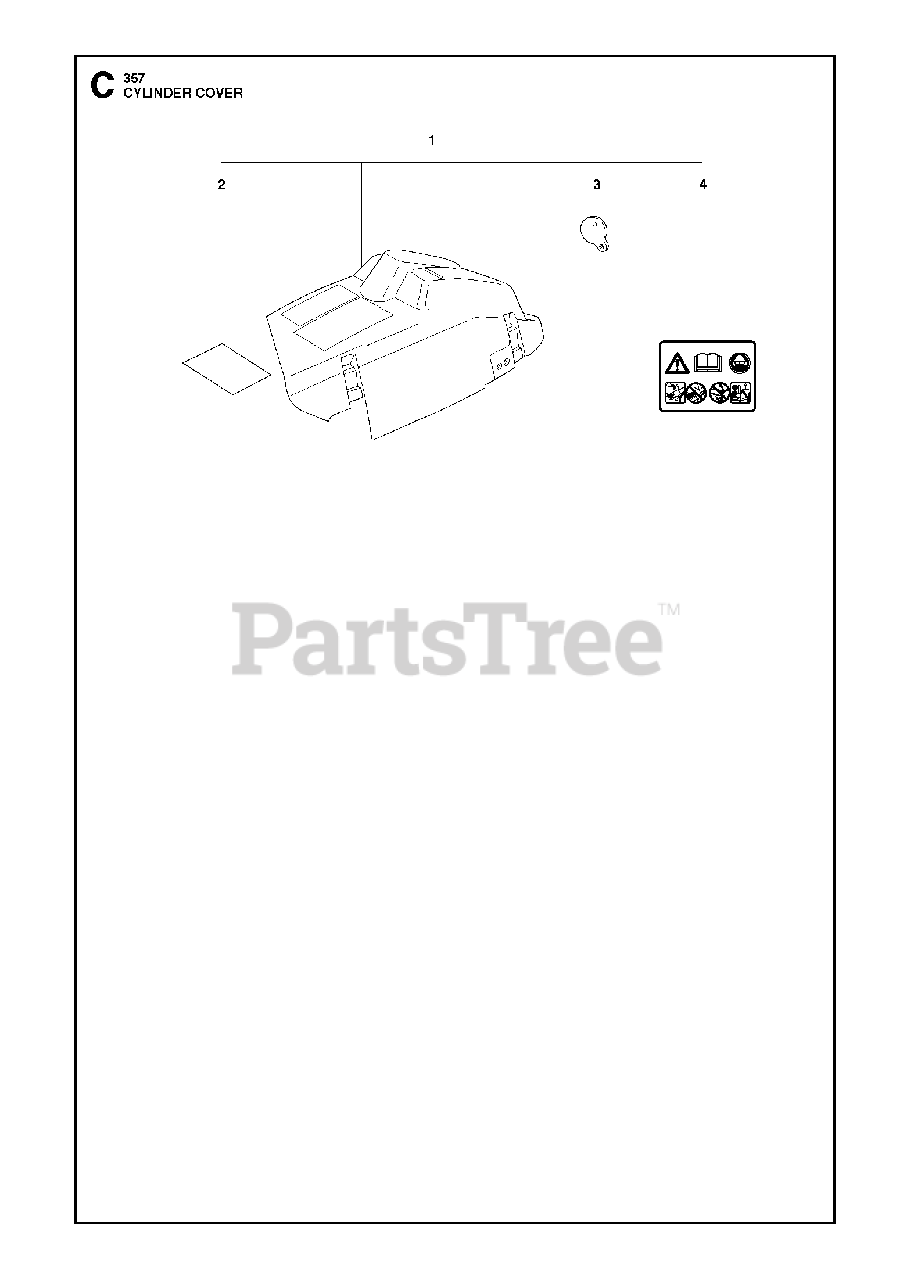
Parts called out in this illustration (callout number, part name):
1	CYLINDER COVER
2	INSULATING FOIL/CYLINDER COVER
3	COVER
